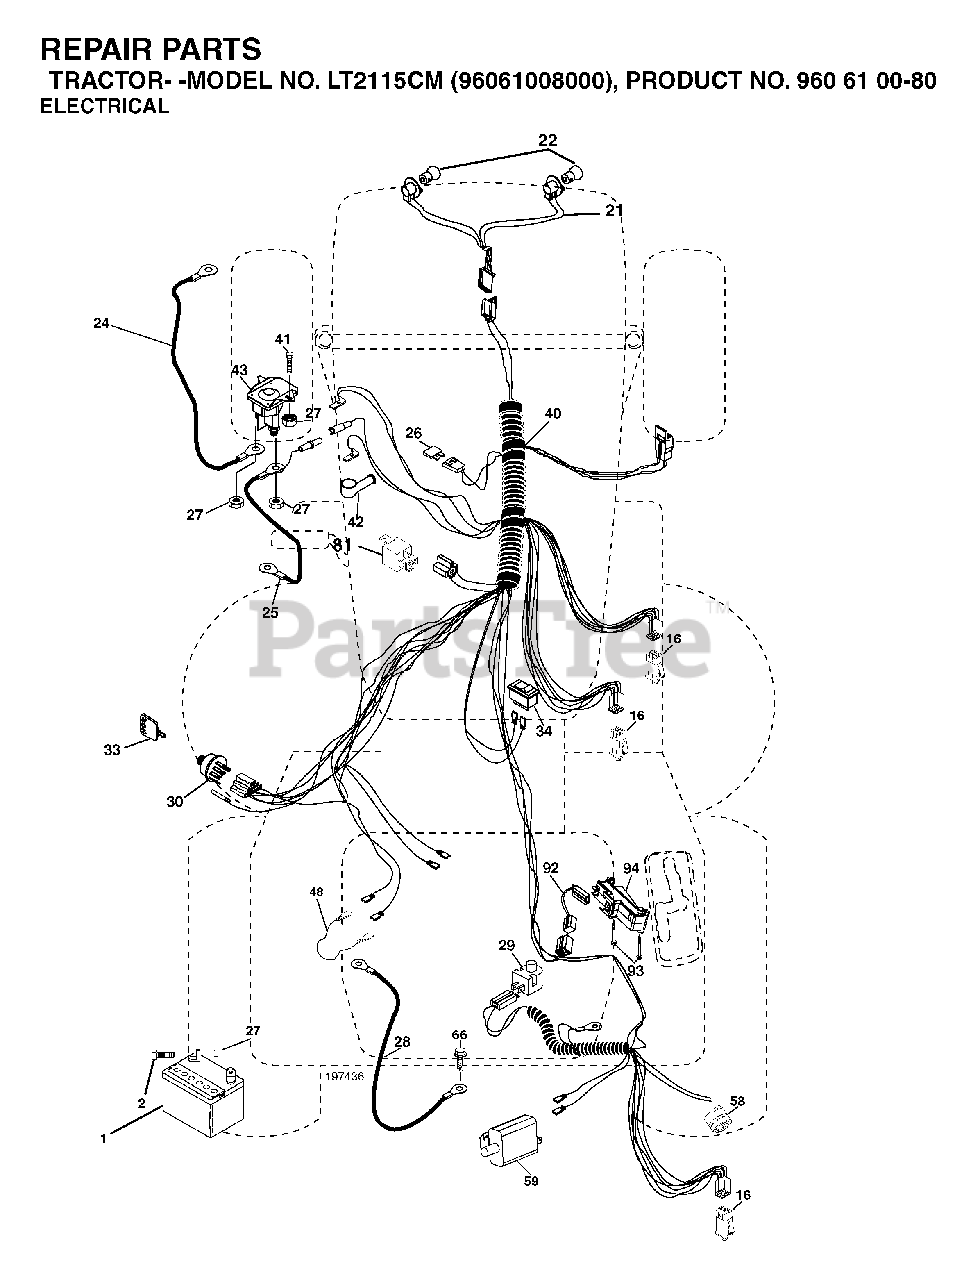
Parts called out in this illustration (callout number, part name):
1	BATTERY 12V .35 AMP
16	SWITCH INTERLOOK PUSH-IN
21	HARNESS ASSY LIGHT
22	LIGHTBULB
24	CABLE ASM
25	CABLE BATTERY
26	FUSE 20AMP
27	NUT
28	CABLE GROUND
29	SWITCH.SEAT.DP W/RAMPS
30	SWITCH.IGN.DELTA.W.LGH.ROS
33	KEY MLD GEN DELTA
34	SWITCH LT
42	TERMINAL COVER
43	SOLENOID.W/BRASS.PLUNG
58	BUZZER
81	RELAY.ASSY.T
92	HARNESS.PIGTAIL.CONSLE
93	SCREW.PLASTITE
94	MODULE.REVERSE.ROS
